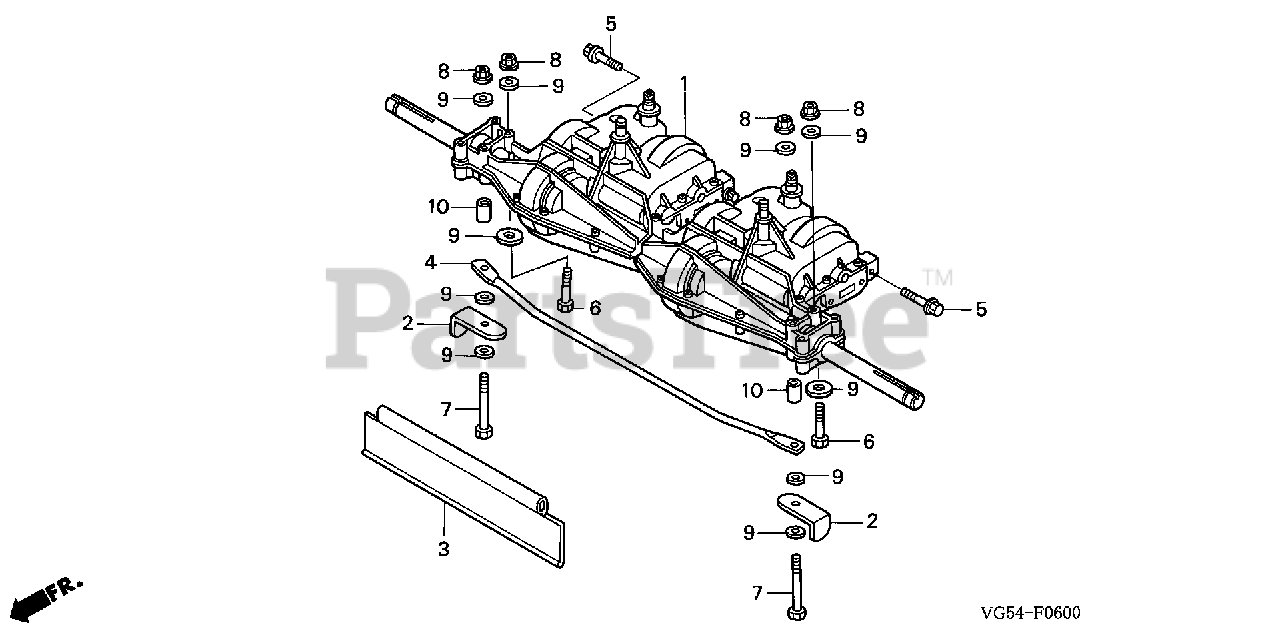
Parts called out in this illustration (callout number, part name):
1	TRANSMISSION ASSY.
2	GUIDE, BAND BRAKE
3	SHIELD, RR.
4	ROD, RR. SHIELD
5	BOLT, SPECIAL (5/16X19")
6	BOLT, HEX. (5/16-18X2) (3/4)
7	BOLT, HEX. (5/16-18X4")
8	NUT, CENTERLOCK (5/16"-18")
9	WASHER, FLAT (5/16")
10	COLLAR, RR. SHIELD
